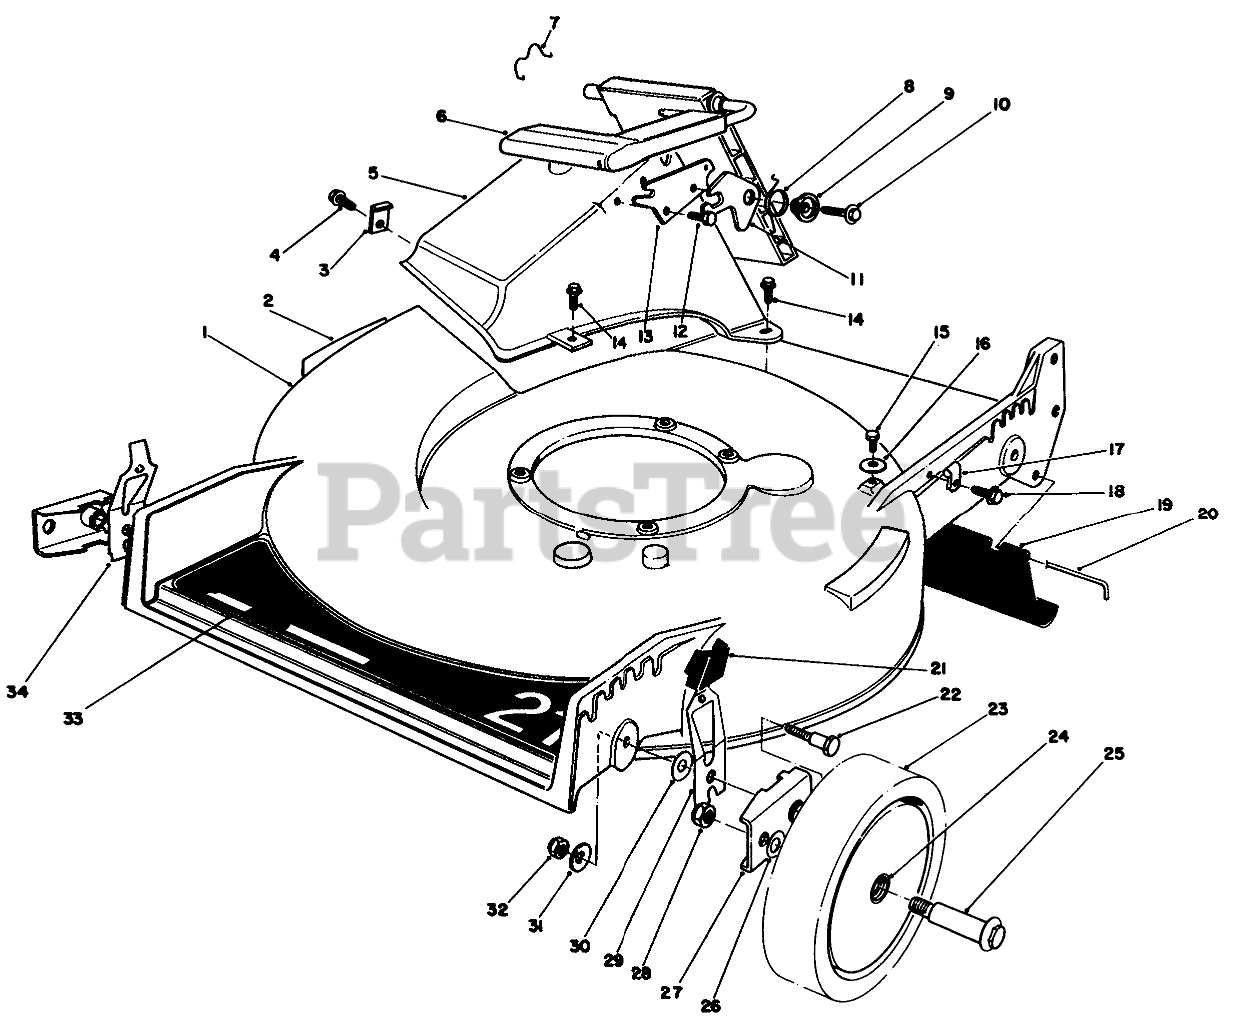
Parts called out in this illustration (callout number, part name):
1	Housing (Incl. Ref. #2)
2	DECAL-DANGER
3	TUNNEL CLIP
4	SCREW
5	Tunnel Discharge
6	Discharge Door Assembly
7	DOOR RET SPRING
8	TORSION SPRING
9	DOOR SPACER
10	SCREW-HWH
11	SAFETY LATCH
12	SCREW-PLASTITE
13	DOOR LATCH PLATE
14	SCREW-HWH
15	SCREW-HWHTF
16	WASHER-FLAT
17	CLAMP-CABLE
18	SCREW
19	SHIELD-TRAILING
20	ROD-SHIELD
21	KNOB-ARM
22	PIVOT SCREW
23	Wheel & Tire Assembly (Incl. Ref. #24)
24	BUSHING
25	WHEEL BOLT
26	WASHER
27	HP PIVOT ARM ASM
28	NUT-LOCK
29	L. HP SPRING ARM ASM
30	WASHER-PIVOT
31	WASHER-BELLEVILLE
32	NUT-LOCK, NI
33	DECK DECAL
34	R HP SPRING ARM ASM
